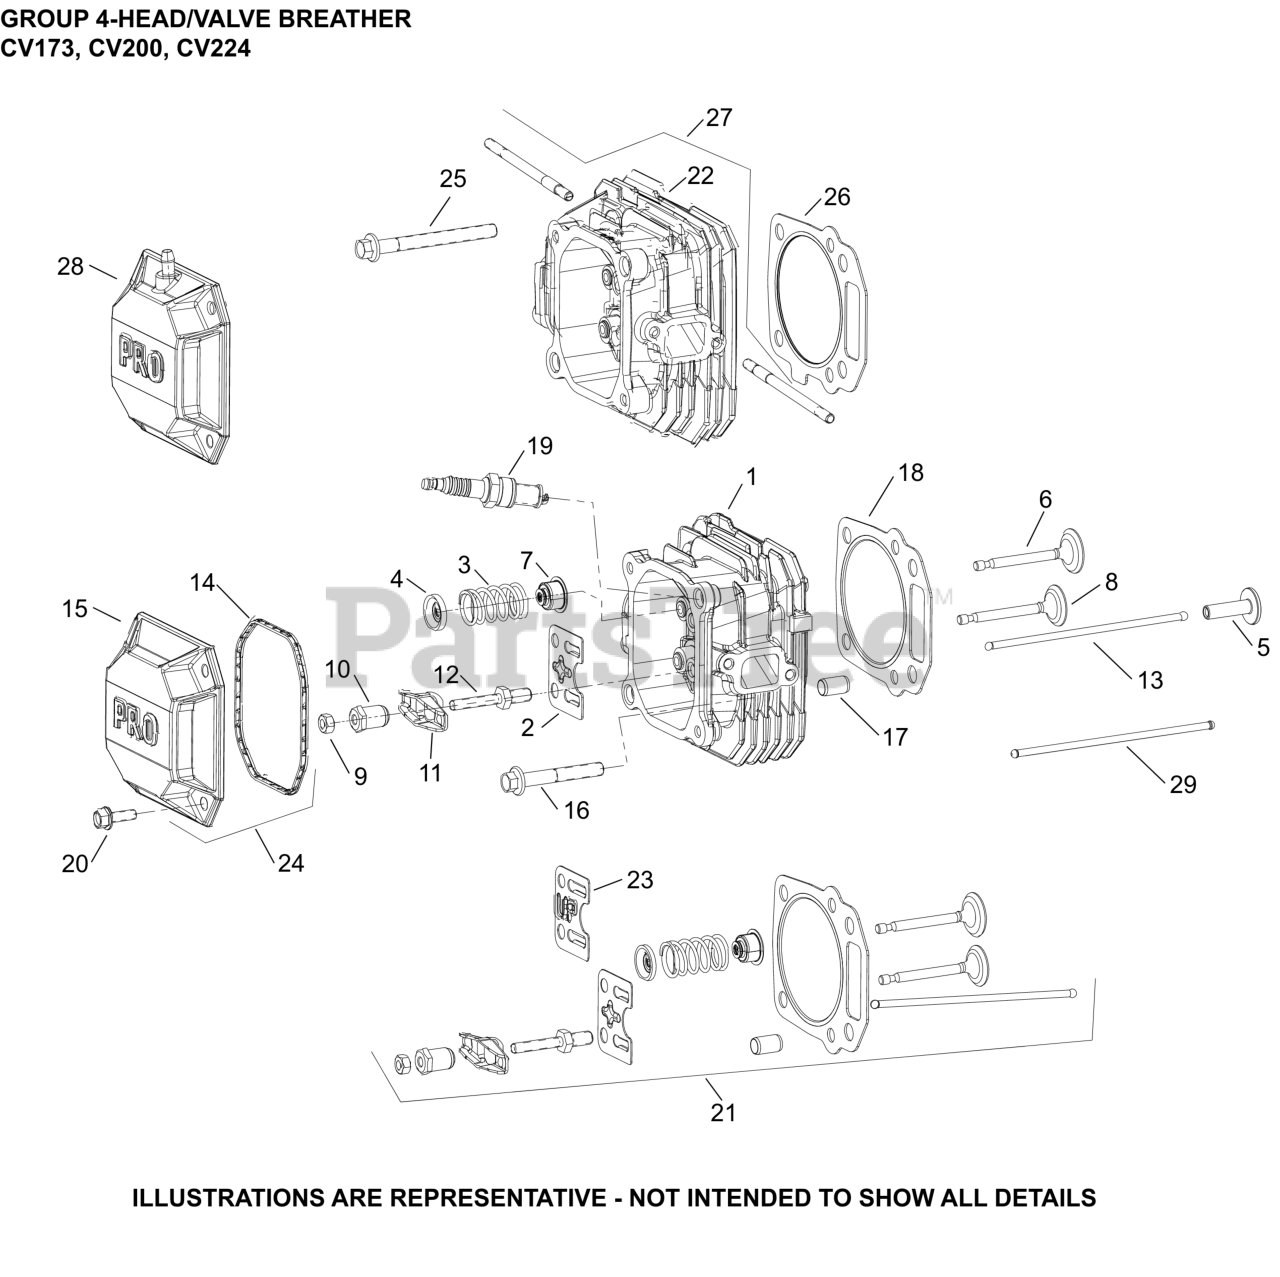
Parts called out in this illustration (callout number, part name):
3	SPRING, VALVE
4	RETAINER, VALVE SPRING
5	LIFTER, VALVE
6	VALVE, INTAKE
7	SEAL, VALVE
8	VALVE, EXHAUST
9	NUT, HEX JAM
10	PIVOT, ROCKER ARM
11	ARM, ROCKER
12	STUD, ROCKER ARM
13	ROD, PUSH-(#1741108S)
14	SEAL, VALVE COVER
15	COVER, VALVE-USE 14 096 184-S
17	DOWEL, CYLINDER HEAD-(#1438013S)
19	PLUG, SPARK 12MM RFI
20	SCREW, HEX FLANGE (M6)
21	KIT, VALVE TRAIN
22	KIT, CYLINDER HEAD-USE 14 818 01-S
23	PLATE, PUSHROD GUIDE
24	COVER, VALVE ASSEMBLY
25	SCREW, HEX FLANGE (M8)
26	KIT, HEAD GASKET
